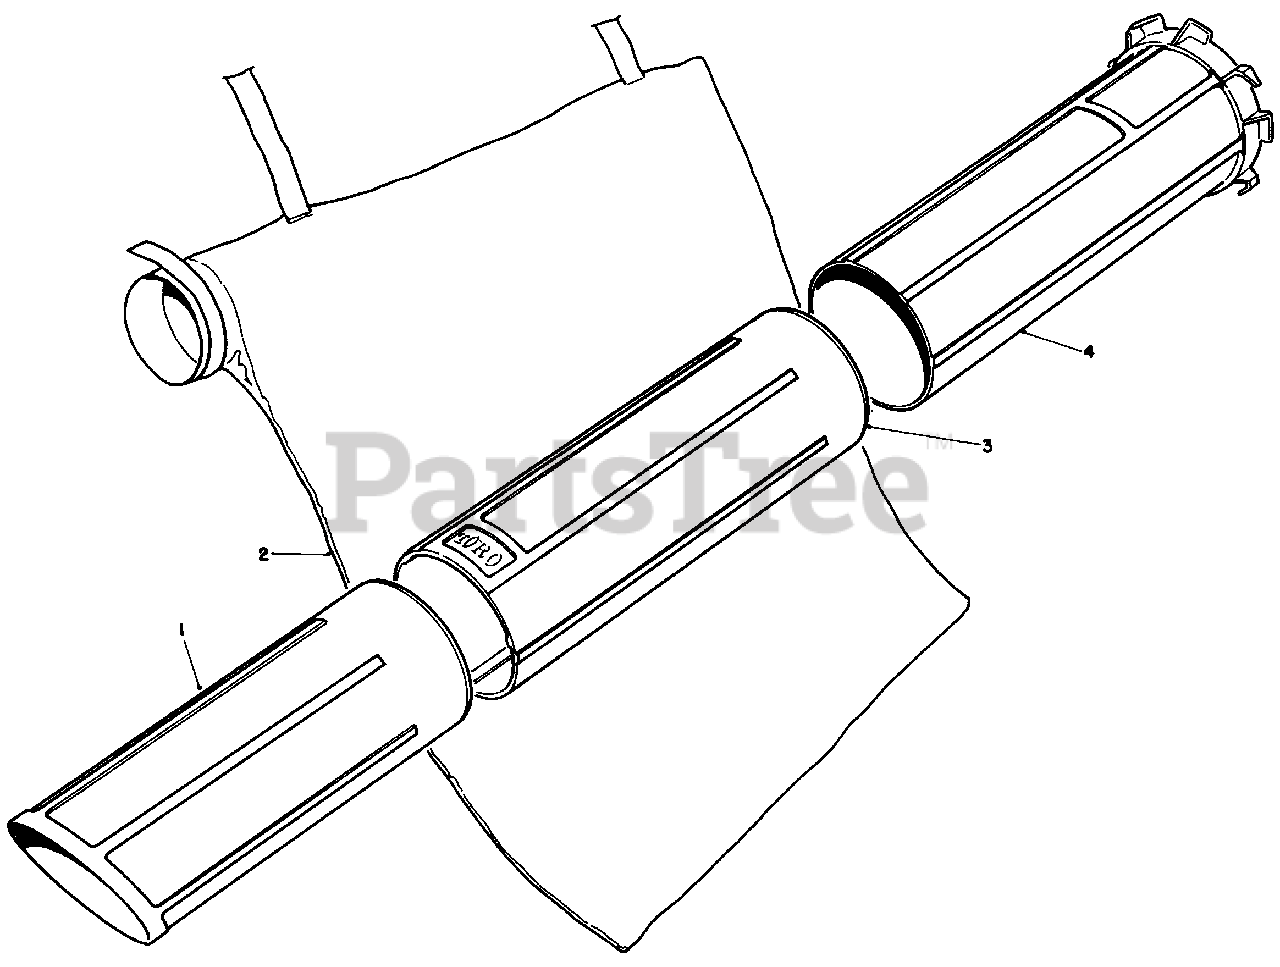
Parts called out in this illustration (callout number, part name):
1	Bag-Vacuum
2	Tube-Vacuum, Upper
3	Tube-Vaccum, Lower
4	Tube-Vacuum, Middle
